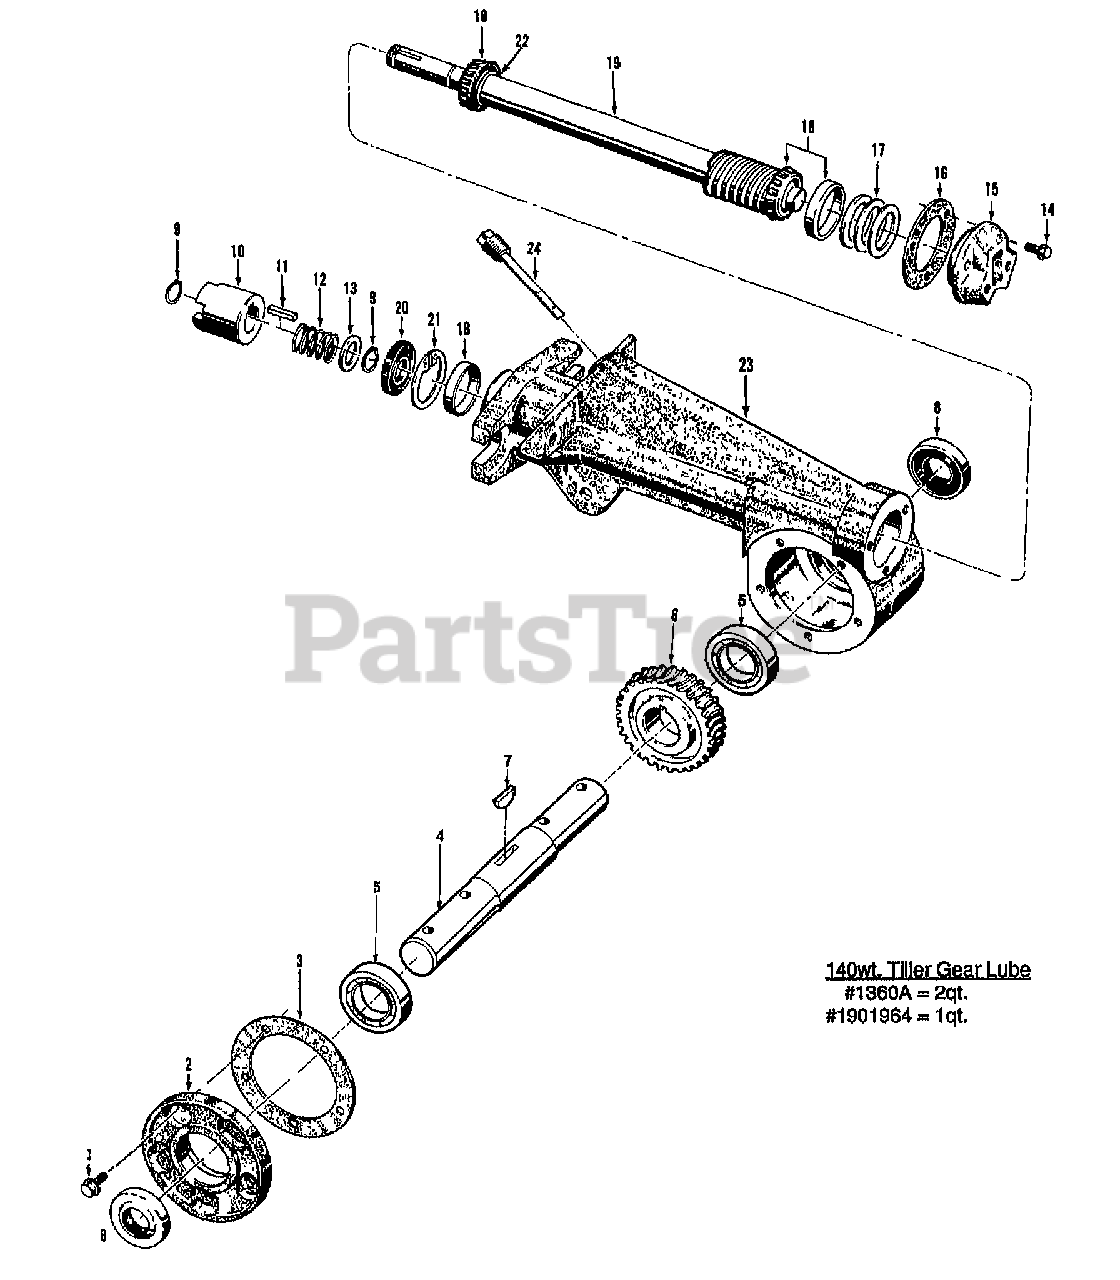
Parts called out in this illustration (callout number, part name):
1	KIT-SEALING SCRS (5)W/LIT
2	COVER-TILLER HSG MACH
3	GASKET-TILLER COVER
4	SHAFT-TILLER MACH HORSE
5	BEARING-BALL
6	GEAR-WORM MACH RTH HORSE
7	KEY-WOODRUFF .25X1.12
8	SEAL-TILLER SHAFT
9	RING-RETAIN EXT .707 ID
10	KIT-CLUTCH DOGS TILLER
10	CLUTCH-DOG HORSE TRANS
11	KEY-.188 SQX1.0
12	SPRING (TC)
13	SHIM-1.0X.7656X.062
14	KIT-SEALING SCRS (3)
15	CAP-REAR #1115
16	GASKET-BRG COVER
17	SHIM-1.75X1.5X.01
17	SHIM-1.75X1.5X.03
17	SHIM-1.75X1.5X.005
17	SHIM-1.75X1.5X.062
18	KIT-BRG CONE&RACE-DRIVESHAFT
19	KIT-TILLER DR SHAFT
20	SEAL-OIL DRIVESHAFT
21	RING-RETAINING 5000-181
22	SHIM-1.0X.7656X.062
23	HOUSING-TILLER W/SLEEVE
24	ASSM-DIPSTICK HORSE TRANS
